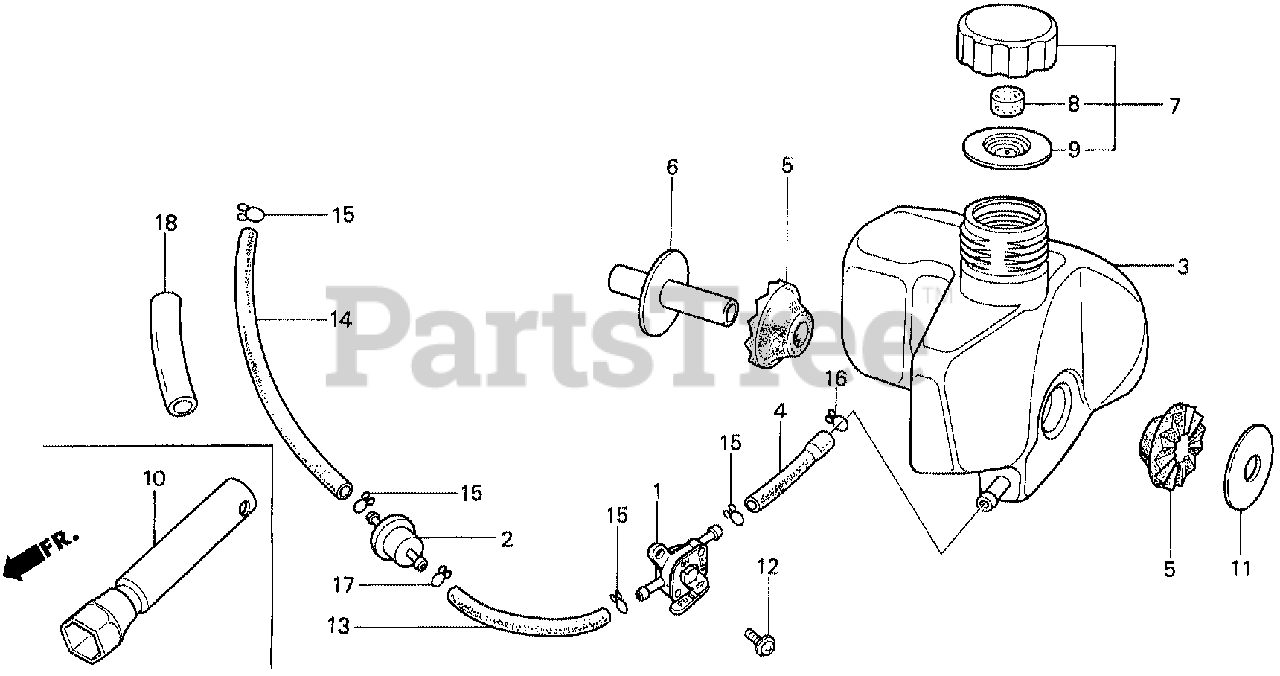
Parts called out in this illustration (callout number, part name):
1	PETCOCK ASSY.
2	STRAINER, FUEL
2	FILTER, FUEL
3	TANK, FUEL
4	TUBE, FUEL (NOT AVAILABLE)
5	RUBBER B, TANK MOUNTING
6	COLLAR, TANK MOUNTING
7	CAP, FUEL TANK
8	SPONGE, FUEL CAP BREATHER
9	GASKET, FUEL CAP
10	WRENCH, SPARK PLUG (NOT AVAILABLE)
11	WASHER, TANK MOUNTING
12	SCREW-WASHER (6X12)
13	BULK HOSE, FUEL (4.5X3000) (4.5X50)
13	BULK HOSE, FUEL (4.5X3000) (4.5X130)
14	BULK HOSE, FUEL (4.5X3000) (4.5X25)
14	BULK HOSE, FUEL (4.5X3000) (4.5X115)
15	CLIP, TUBE (B8)
16	CLIP, TUBE (B10)
17	CLIP, TUBE (B8)
17	CLIP, TUBE (C9)
18	COVER, TUBE (NOT AVAILABLE)
18	BULK HOSE, VINYL (12X16X3000)
